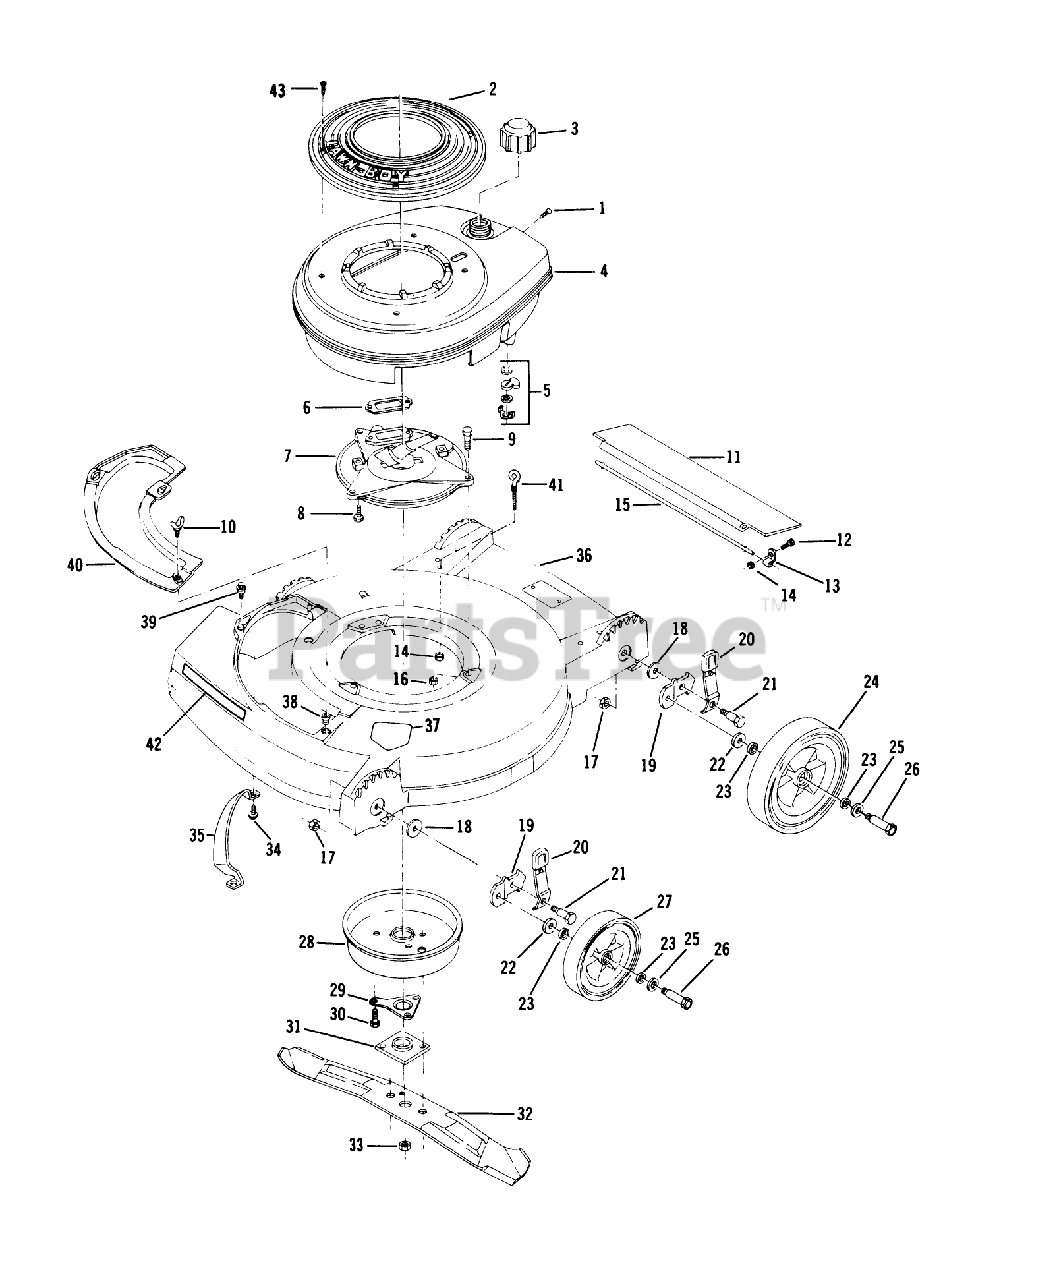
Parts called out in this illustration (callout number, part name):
1	SCREW S
3	FUEL CAP & INSERT
5	SHUT OFF VALVE KIT
7	PLATE F
8	SCREW V
9	SCREW-HH
10	WING SCREW LAWRE
13	CLAMP ROD KMC
14	LOCKNUT E
15	ROD T/SHIELD ADV WIRE
16	NUT-LOCK F
17	LOCKNUT
18	WASHER
20	SPRING ARM ASM
21	BOLT
22	WASHER WROUGHT
23	WASHER
25	SPACER
26	BOLT WHEEL
27	WHEEL & TIRE KIT
28	MUFFLER COVER F
29	SUPPORT F
30	SCREW
31	PLATE AND COLLAR ASM
33	NUT-BLADE
35	TOE BAR 19"
41	BOLT-EYE
43	SCREW - SELF TAPPING
